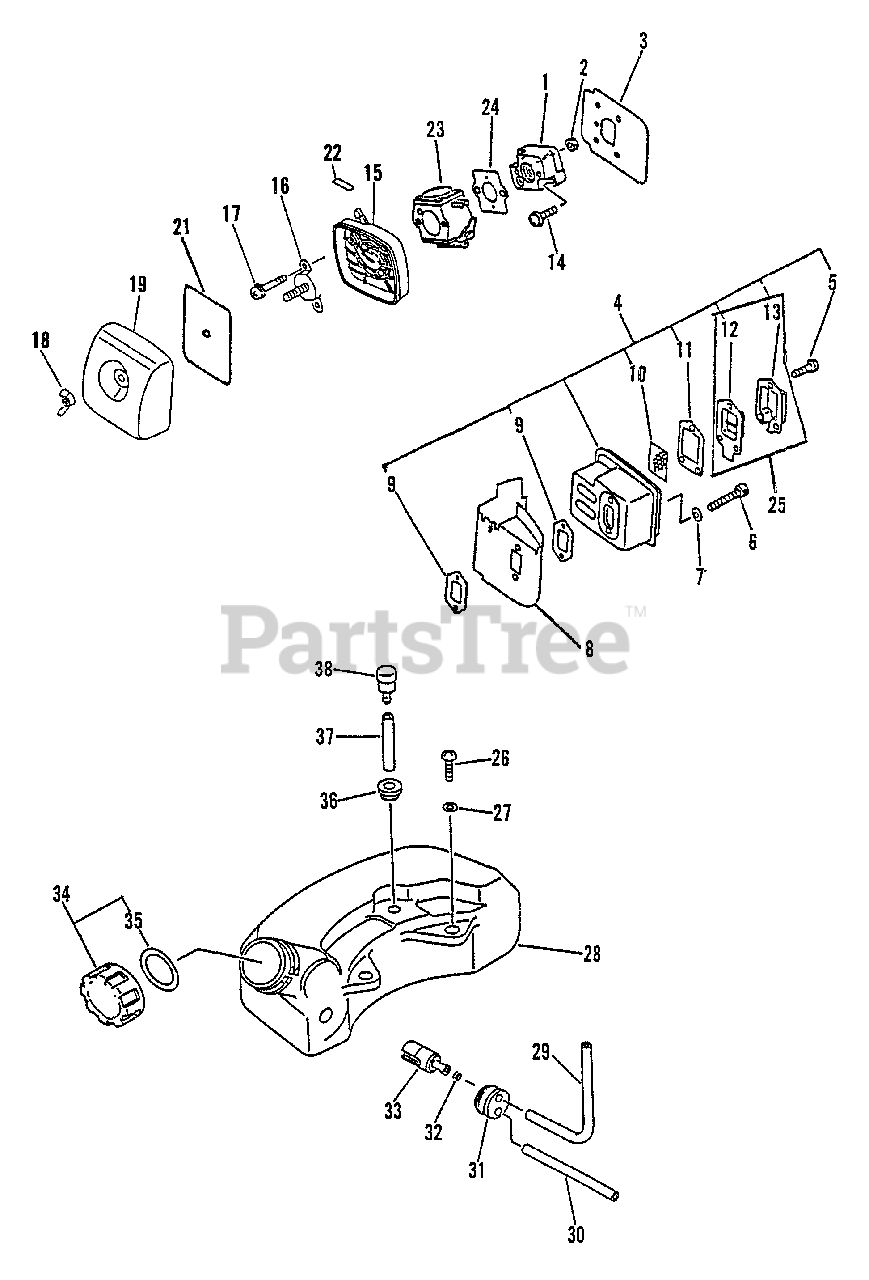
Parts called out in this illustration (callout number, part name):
1	INSULATOR, INTAKE
2	NUT M5
3	HEAT SHIELD, INTAKE
4	MUFFLER ASSY
5	SCREW 4×10
6	BOLT 5×55
7	WASHER, FLAT 5.5×10×0.8
8	COVER, EXHAUST
9	GASKET, EXHAUST
10	SCREEN, SPARK ARRESTER
11	GASKET, EXHAUST
12	GUIDE, EXHAUST
13	GUIDE, EXHAUST - INNER
14	SCREW 5×20
15	CASE ASSY, AIR FILTER
16	PLATE, PREVENT
17	SCREW 5×65
18	WINGNUT - 6
19	COVER, AIR FILTER - BLACK
21	FILTER, AIR
22	LABEL, CHOKE
23	CARBURETOR - C1U-K18
24	GASKET, INTAKE
25	GUIDE, EXHAUST - INNER
26	SCREW 5×16
27	WASHER 5.5×12×0.8
28	TANK, FUEL
29	PIPE, FUEL
30	PIPE, FUEL RETURN 3×6×110
31	GROMMET, FUEL
32	CLIP 6 MM
33	FILTER, FUEL
34	CAP ASSY
35	GASKET, FUEL CAP
36	GROMMET
37	PIPE, FUEL
38	VENT ASSY
